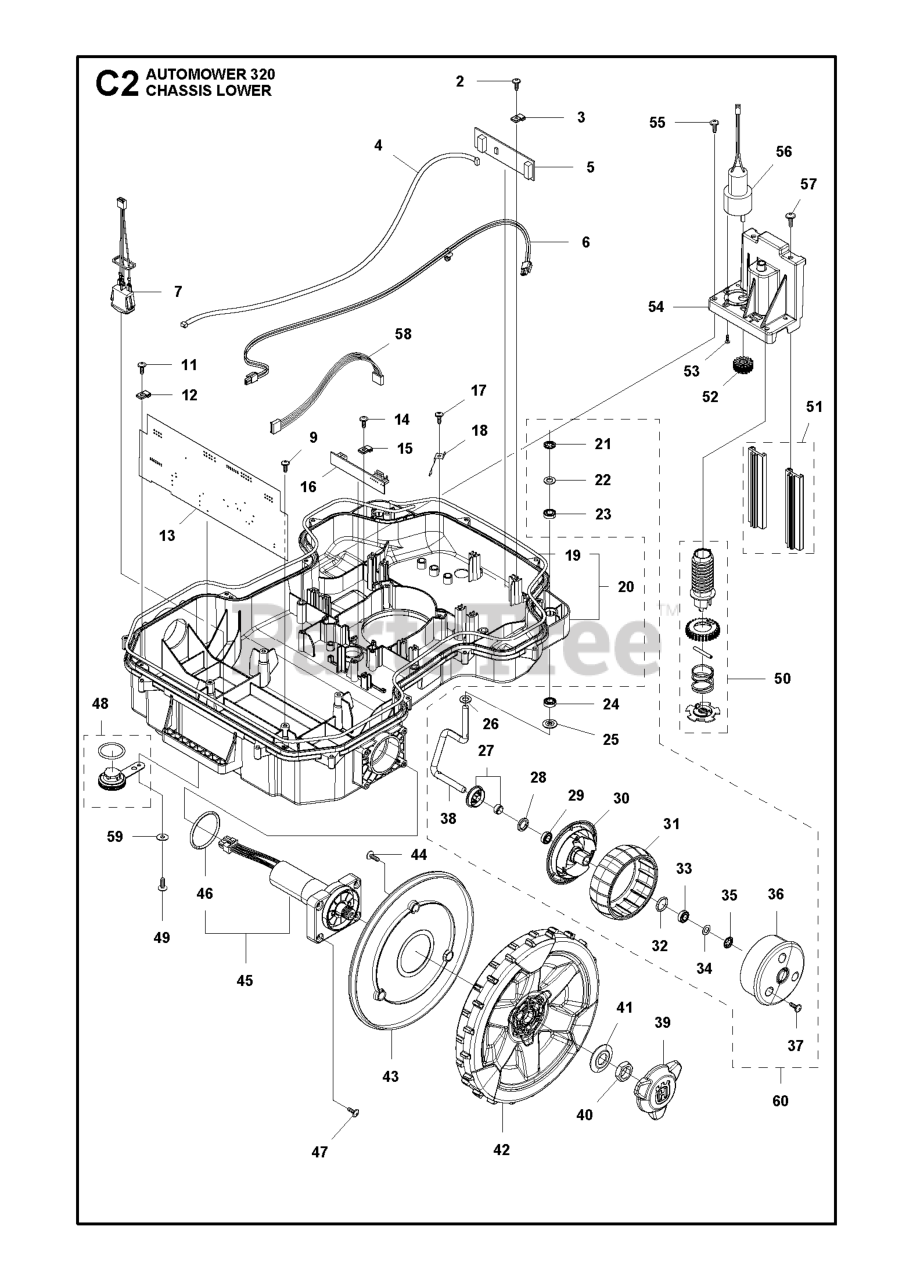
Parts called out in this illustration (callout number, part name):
1	BATTERY LI-ION
2	SCREW 14MM
4	LOOM LOOP SENSOR
5	PRINTED CIRCUIT ASSY PCBA LOOP
7	LOOM ON/ OFF
9	SCREW ITXPANT
10	HOLDER TWIST LOCK
11	SCREW 14MM
14	SCREW 14MM
17	SCREW 14MM
18	SPRING GUIDE HEIGHT ADJUSTMENT
19	SEALING STRIP
21	LOCK WASHER PUSH-ON TYPE P 8 S
22	WASHER DIN 988 13X8X0.5
23	BALL BEARING SINGLE ROW S688
24	BALL BEARING SINGLE ROW S688
25	WASHER FRONT WHEEL CENTER HOLE
26	WASHER DIN 988 13X8X0.5
27	SHIELD KIT
28	SEALING 12X18X3
29	BALL BEARING SINGLE ROW S688
30	WHEEL FRONT WHEEL INSIDE
31	WHEEL RUBBER TYRE
32	O-RING 2,62X15,54
33	BALL BEARING SINGLE ROW S688
34	WASHER DIN 988 13X8X0.5
35	LOCK WASHER PUSH-ON TYPE P 8 S
36	WHEEL FRONT WHEEL OUTSIDE
37	SCREW 14MM
38	SPINDLE SPINDLE FRONT WHEEL RI
39	HUB CAP REAR WHEEL NO CENTER P
40	HEXAGON THIN NUT
41	WASHER WASHER REAR WHEEL 16X40
42	WHEEL ASSY D249 HVA LIGHT GREY
43	COVER REAR WHEEL
44	SCREW 14MM
47	SCREW ITXPANT
49	SCREW 14MM
51	BEARING KIT
55	SCREW 14MM
58	LOOM HEIGHT ADJUSTMENT
60	WHEEL KIT FRONT
